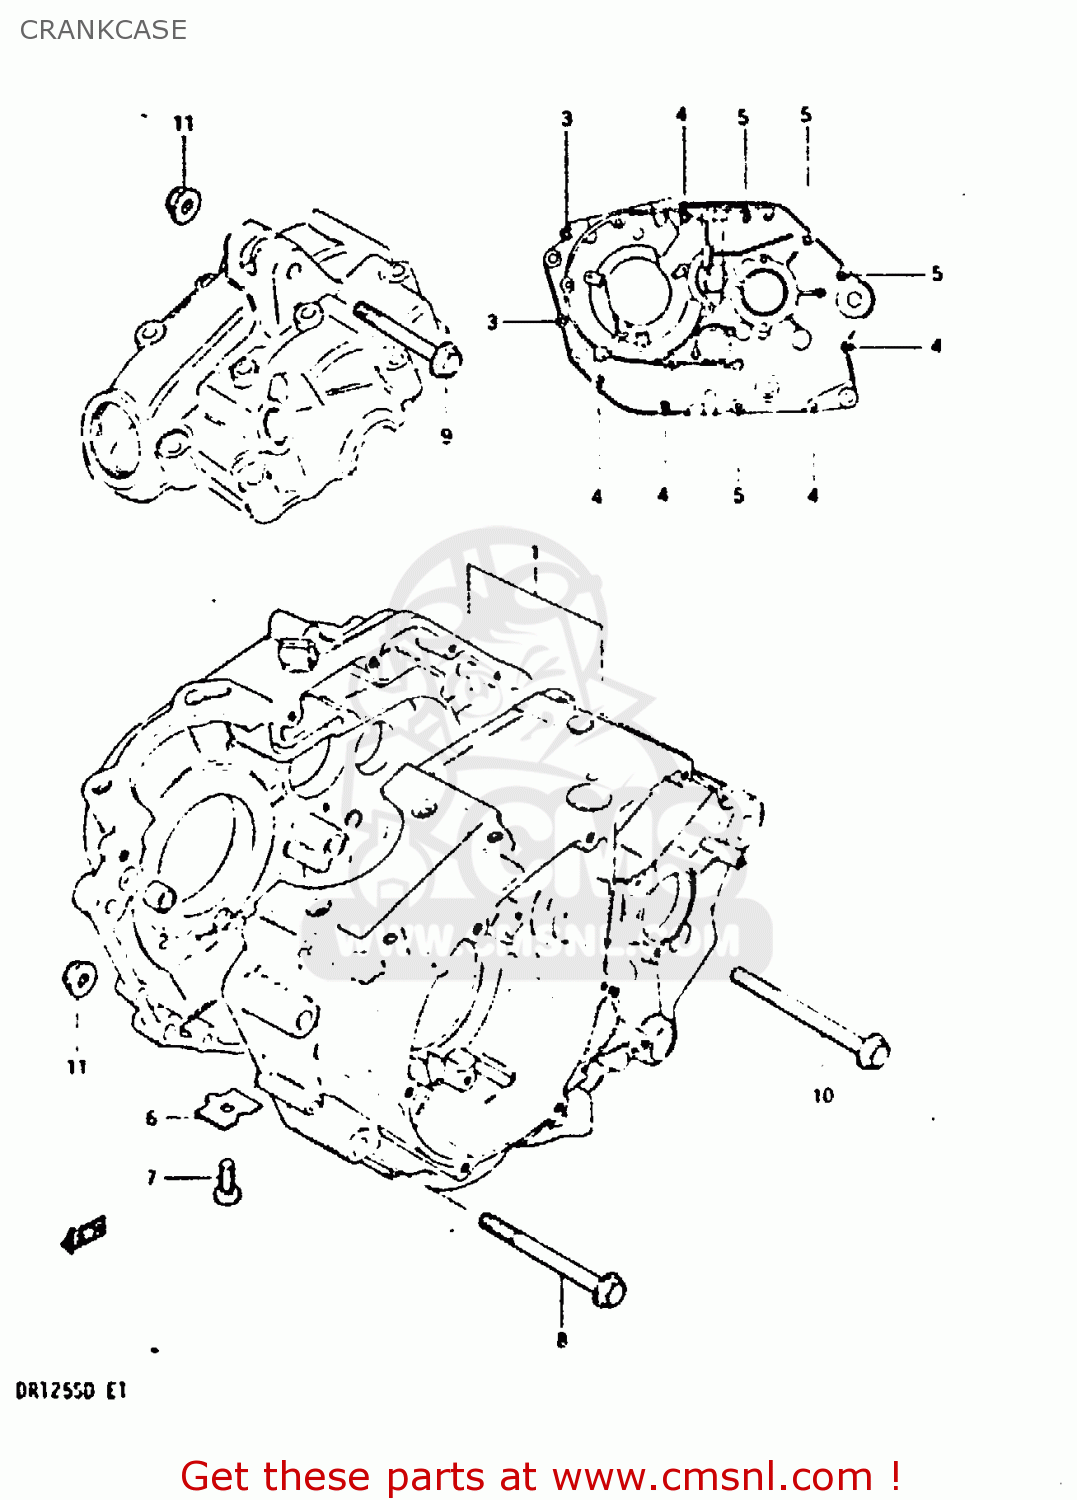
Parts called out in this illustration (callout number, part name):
1	CRANKCASE SET
2	PIN
3	BOLT (6X45)
4	BOLT (6X60)
5	BOLT (6X75)
6	PLATE,OIL GALLERY PLUG
7	BOLT
8	BOLT(8X80)
9	BOLT 8X50
10	BOLT 8X88
11	NUT
